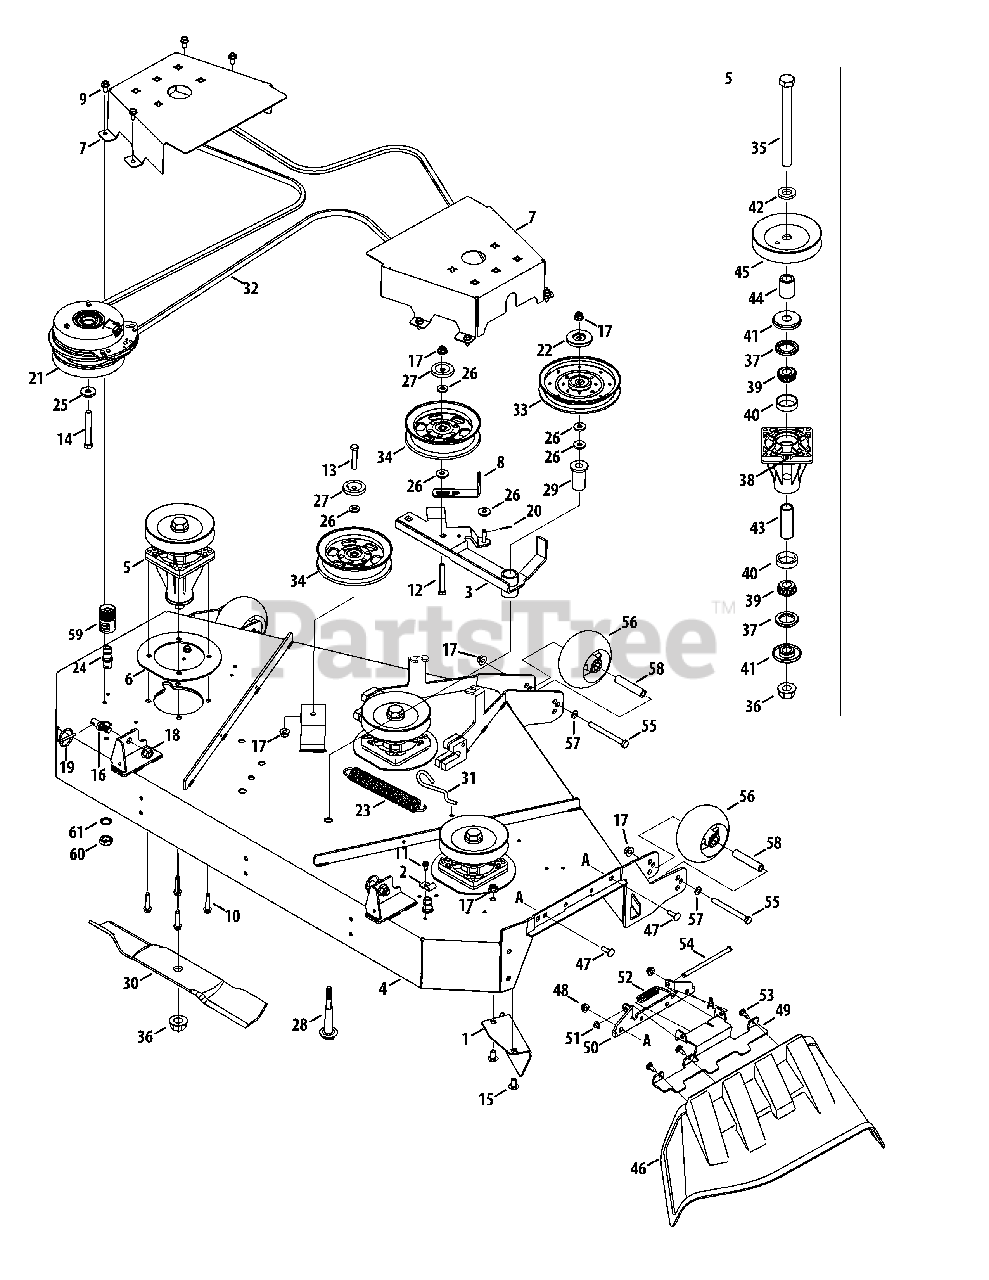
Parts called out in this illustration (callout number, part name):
1	Chute Baffle
2	Bracket, Hook Retainer
3	Deck Idler Assembly
4	54" Deck
5	Spindle Assembly
6	Spindle Reinforcement Plate
8	Bracket, Deck Keeper
9	Hex Washer Screw, 5/16-18 x .750
10	Hex Washer Screw, 5/16-18 x 1.50
11	Hex Washer Screw, 1/4-20 x .500
12	Hex Cap Screw, 3/8-16 x 2.50
13	Hex Cap Screw, 3/8-16 x 2.00
14	Screw, 7/16-20 x 3.25
15	Carriage Screw, 3/8-16 x .75
16	Pin, Shoulder Lock, .500
17	Flange Lock Nut, 3/8-16
18	Flange Lock Nut, 1/2-13
19	Pin, Lynch x .1875
20	Cotter Pin 3/32" Dia. x .75 Lg.
21	Electric PTO Clutch
22	Pulley Cap
23	Extension Spring, 1.25 OD x 1.751
24	Deck Water Nozzle
25	Flat Washer, .450 x 1.25 x .164
26	Flat Washer, .406 x .875 x .105
27	Pulley Cap
28	Shoulder Boult, .625 x 2.12, 3/8-16
29	Shoulder Spacer, 1.055 x .627 x 2.292
30	Blade, 19.00
31	Deck Spring Rod
33	Idler Pulley, 6.00 Dia
34	Idler Pulley, 5.00 Dia.
35	Hex Cap Screw, 3/4-16 x 8.25
36	Nut, 3/4-16, Flangelock
38	Grease Fitting
39	Cone Bearing
40	Cup Bearing
41	Spindle Spacer
42	Spacer, .812 ID x .218 LG
43	Spacer, .78 x 1.00 x 2.895
44	Spacer, .792 x 1.20 x 1.628
45	V-Type Pulley
46	Discharge Chute Assembly
47	Carriage Bolt, 5/16-18 x 1.00
48	Flange Lock Nut, 5/16-18
51	Push Cap
52	Torsion Spring
53	Shoulder Screw, 1/4-20
54	Chute Rod
55	Hex Cap Screw, 3/8-16 x 4.0
56	Deck Ball Wheel, 5.0
57	Flat Washer, .406 x .875 x .059
58	Wheel Spacer
59	Water Nozzle Adapter
60	Hex Nut, M-16 x 1.5
61	Lock Washer, 17 x 23.8 x 1.95
